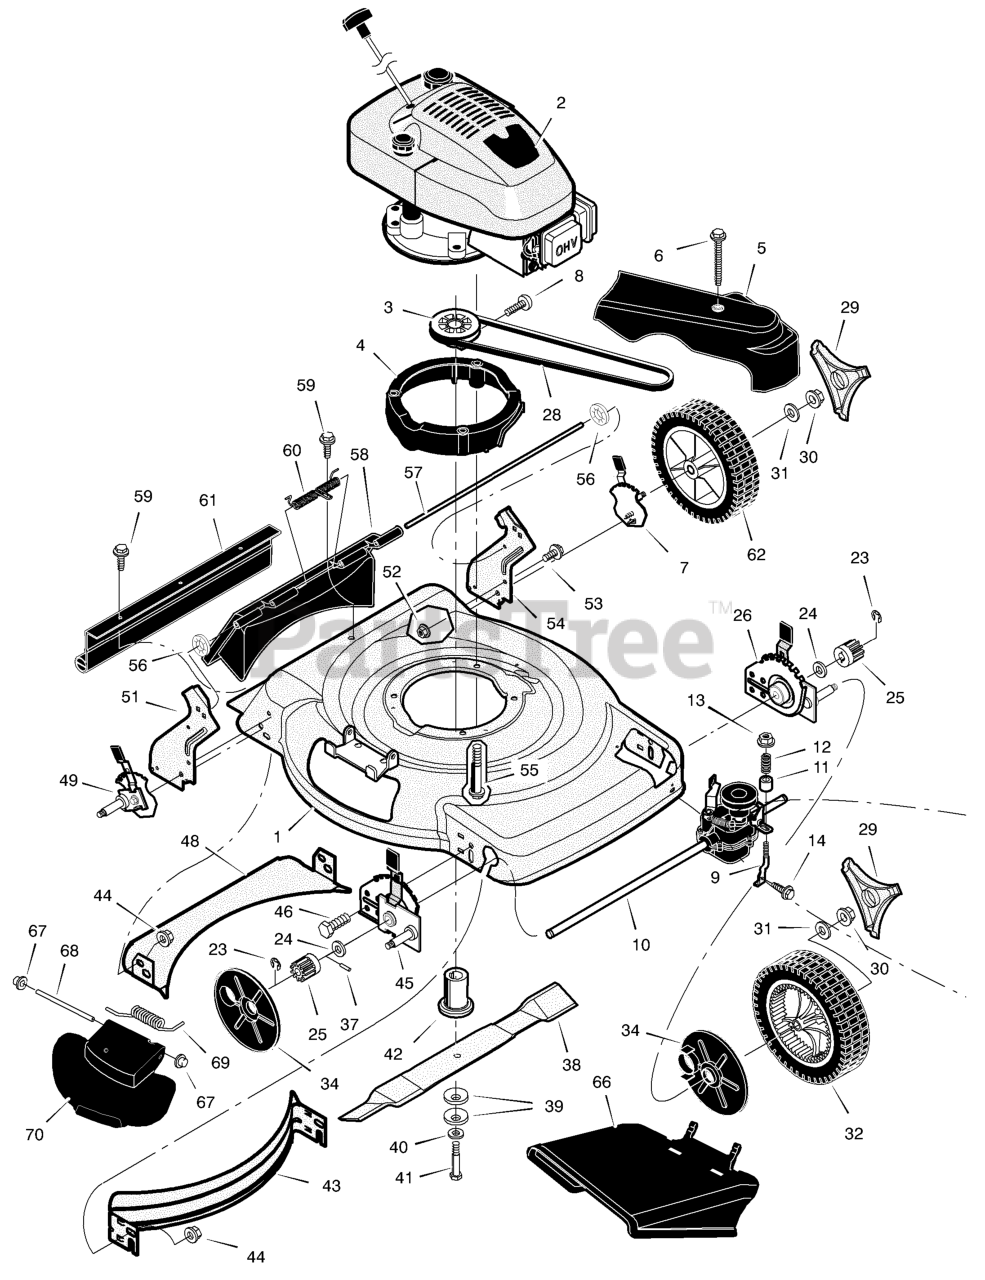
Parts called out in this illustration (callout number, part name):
1	Housing
2	Engine *
3	Pulley, Drive
4	Spacer, Engine
5	Cover, Belt (Black)
7	Adjuster, Left Rear Height
9	Support, Rod
10	Transmission *
12	Spring, Compression
13	Nut
25	Gear, Pinion
26	Adjuster, Left Front Height
29	Cap, Hub
30	Nut, Flange
31	Washer
32	Wheel & Tire, Front
34	Cover, Dust
37	Pin, Drive
39	Washer, Belleville
42	Adapter, Blade
43	Baffle, Front
44	Nut, Flange
45	Adjuster, Right Front Height
46	Bolt
48	Baffle, Rear
49	Adjuster, Right Rear Height
51	Bracket, Right Handle
52	Nut, Flange
53	Bolt
54	Bracket, Left Handle
55	Bolt, Engine
56	Retainer
57	Rod, Pivot
58	Door, Rear (Black)
60	Spring
61	Guard, Rear
62	Wheel & Tire, Rear
66	Deflector, Chute
67	Push On Cap
68	Rod, Pivot
69	Spring, Torsion
70	Cover, Mulch (Black)
